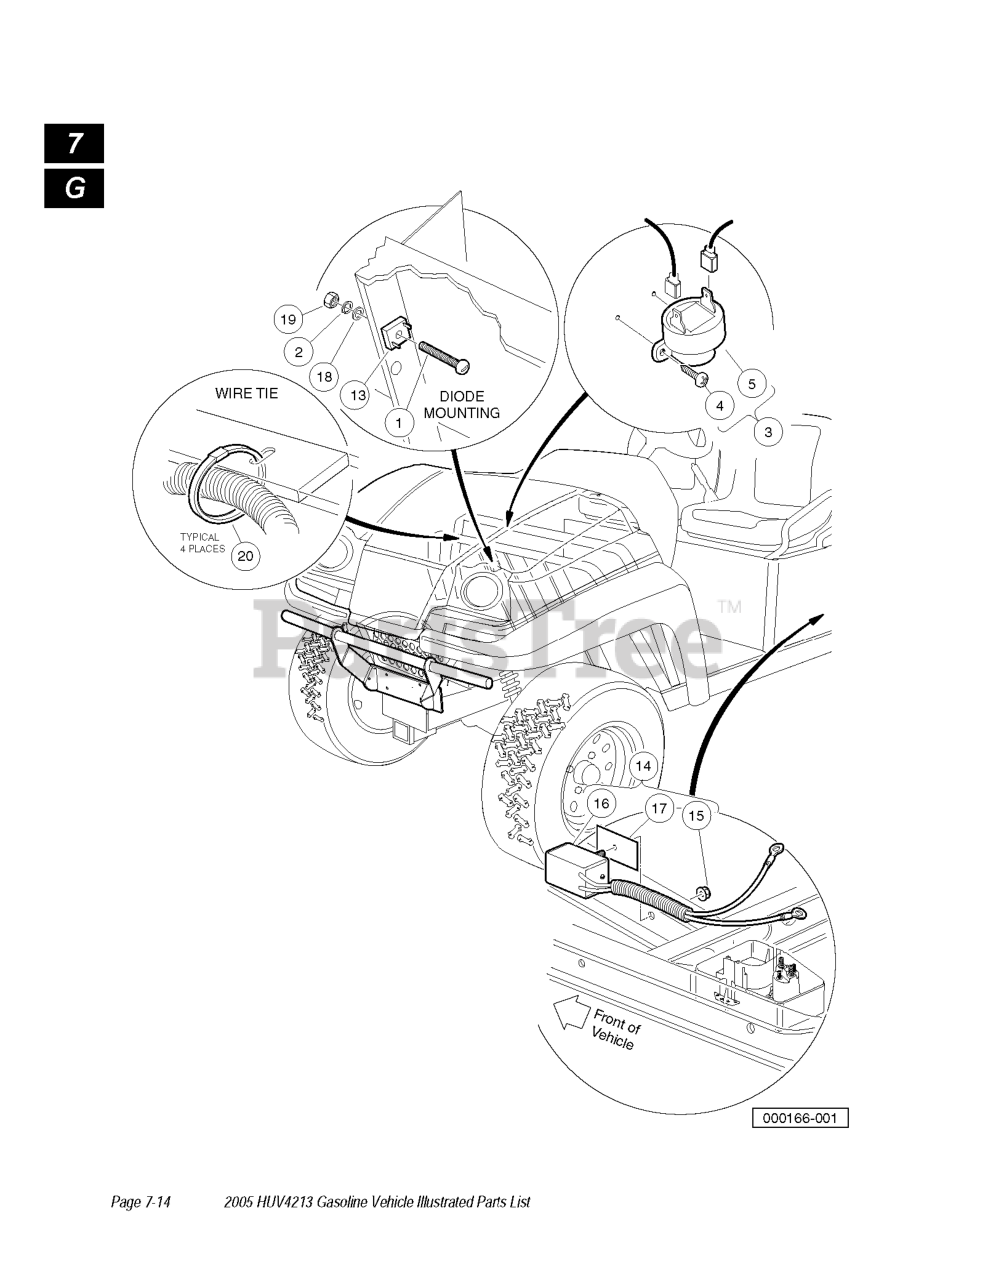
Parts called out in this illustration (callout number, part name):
1	SCREW HD MCH
2	WASHER,#10 SPLIT WASH
3	KIT, REVERSE BUZZER
4	LOCKNUT, #6-32 WHIZ
6	SCREW #6-32X1/2HX WASH HEAD
7	SCREW, #4-24 X .33 PN HD MACH
8	BUZZER, 9-48 VDC REVERSE
10	SCREW, #4-40 X .75 RD HD MACH
11	NUT HEX MACHINE
12	LOCKWASH, # 4 HELICAL SPLIT
13	LIMITER, VOLTAGE
14	KIT, DIODE
15	LOCKNUT, 5/16-18 HEX FLANGE
16	DIODE ASSY
17	THERMAL, PAD
18	WASHER FLAT
19	NUT, #10-32 HEX
20	TIE WRAP , 11" NYLON
